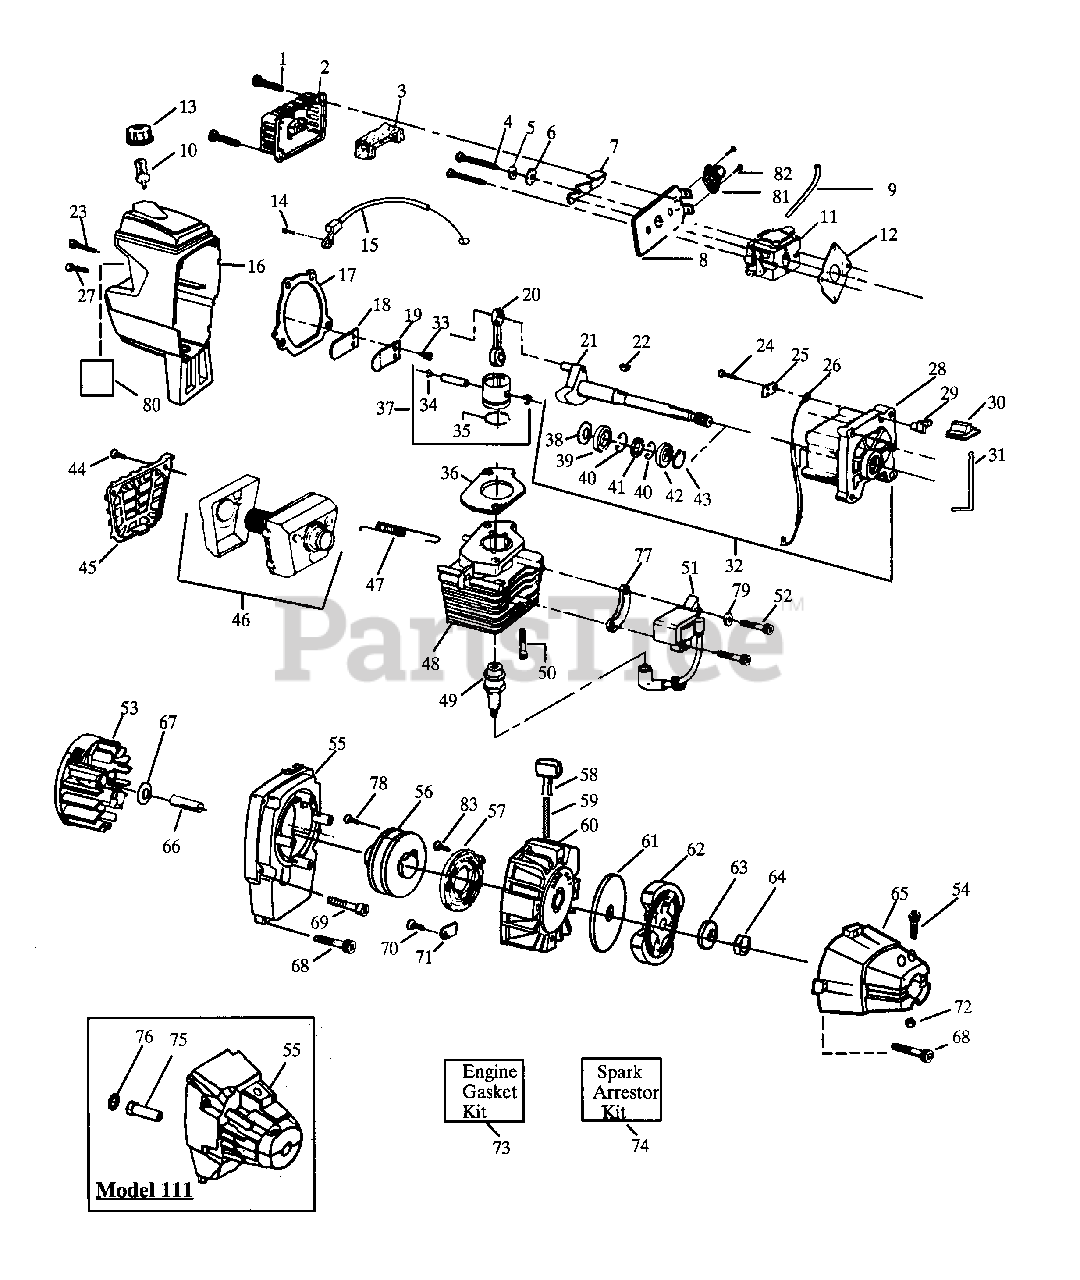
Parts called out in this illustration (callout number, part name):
2	Air Filter Cover
3	Air Filter
6	Wave Washer
7	Choke Shutter, Type 1
7	Choke Shutter, Type 2 & 3
8	Air Filter Plate, Type 1
8	Air Filter Plate, Type 2 & 3
9	Fuel Line Kits, Fuel Line
9	Fuel Line Kits, Return Line 114 Type 2-3
10	Fuel Pick-up Ass'y.
11	Carburetor, Model 111 (WA-217)
11	Carburetor, Model 114 (WA-199) Type 1 & 2
11	Carburetor, Model 114 (WT-298A) Type 3
12	Carburetor Gasket
13	Fuel Cap Ass'y.
15	Throttle Cable Ass'y., Model 111
15	Throttle Cable Ass'y., Model 114
16	Shroud & Tank Ass'y., Type 1
16	Shroud & Tank Ass'y., Type 2 & 3
17	Crankcase/Shroud Gasket
19	Reed Stop
20	Connect Rod Ass'y.
21	Crankshaft Ass'y. -See Ser. Ref. 2, Model 111
21	Crankshaft Ass'y. -See Ser. Ref. 2, Model 114
22	Flywheel Key
25	Switch Insulator
26	Lead Wire
28	C'case Ass'y.
29	Switch Ramp
30	Switch Button
31	Switch Spring
32	Crankcase & Crankshaft Ass'y (21, 28 & 39-43), Model 111
32	Crankcase & Crankshaft Ass'y (21, 28 & 39-43), Model 114
34	Piston Pin Retainer
35	Piston Ring, Model 111
35	Piston Ring, Model 114
36	Cylinder Gasket
37	Piston Kit
39	Inner Bearing
40	Retaining Ring
41	Crankshaft Seal
42	Outer Bearing
43	Crankshaft Retaining Ring
45	Muffler Guard
46	Muffler Kit
47	Muffler Attachment Spring
48	Cylinder, Model 111
48	Cylinder, Model 114 Type 1 & 2
48	Cylinder, Model 114 Type 3
49	Spark Plug, Type 1 & 2
49	Spark Plug, Type 3 (RCJ-8Y)
51	Ignition Module Kit
52	Screw, Model 111
52	Screw, Model 114
53	Flywheel Ass'y., Model 111
53	Flywheel Ass'y., Model 114
55	Fan Housing, Model 111
55	Fan Housing, Model 114
56	Starter Pulley Kit
57	Starter Spring
58	Starter Handle
59	Rope Kit
60	Pulley Housing Ass'y. (114 Only)
61	Clutch Washer (114 Only)
62	Clutch (114 Only)
63	Washer (114 Only)
64	Nut (114 Only)
65	Clutch Housing (114 Only)
66	Spacer (114 Only)
67	Washer (114 Only)
71	Retainer
73	Engine Gasket Kit (Inc. 12,17,36)
74	Spark Arrestor Kit
75	Drive Coupling (111 Only)
76	Washer (111 Only)
77	Spacer (111 Only)
80	Instruction Decal, Type 1
80	Instruction Decal, 114 Type 3
81	Primer Bulb Ass'y 114 Type 2-3
82	Screw-Primer 114 Type 2-3
83	Screw-Starter Sprg. 114 Type 3
